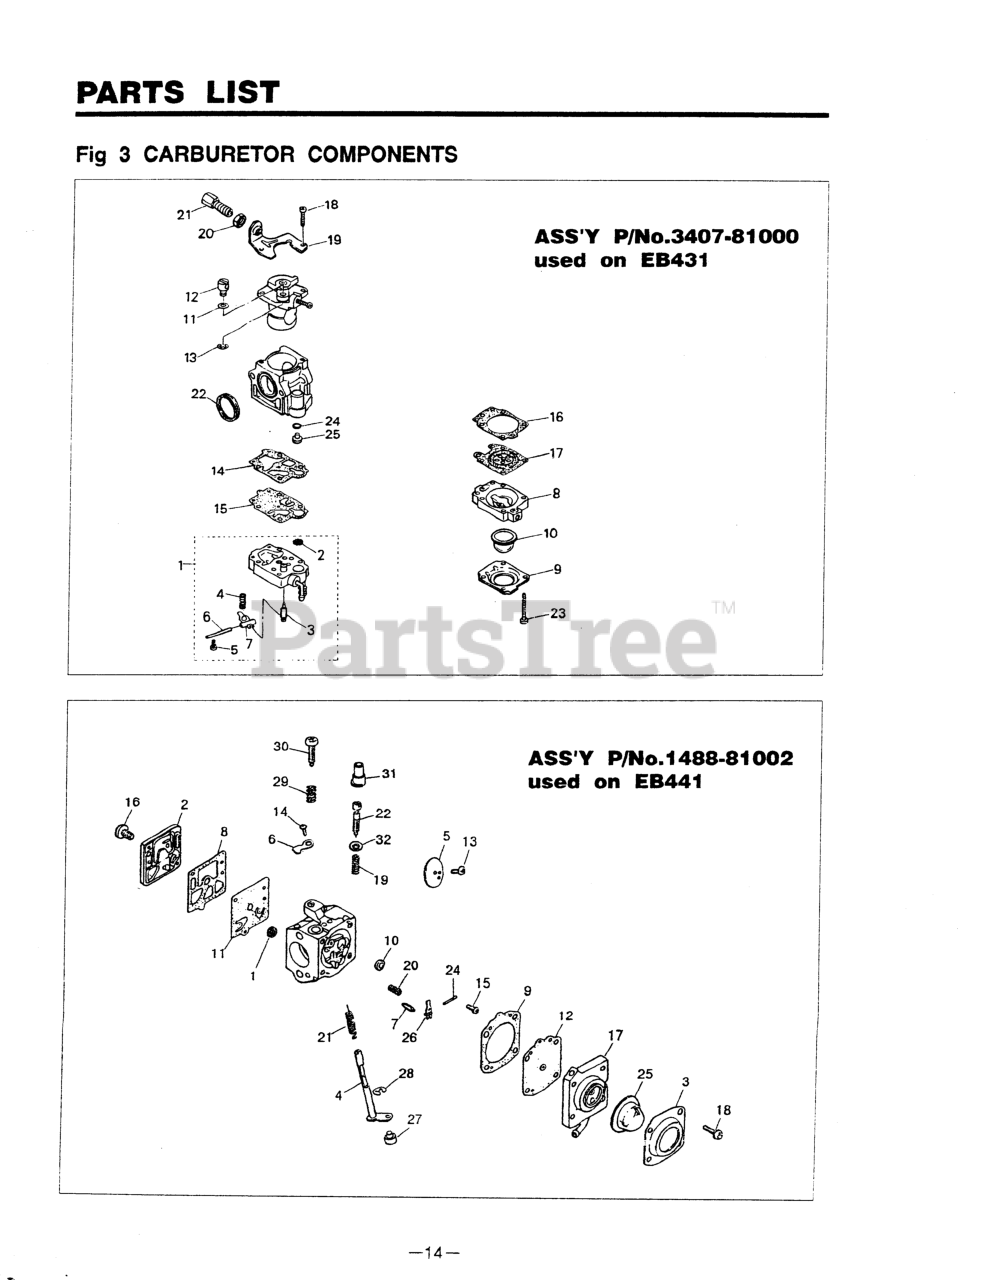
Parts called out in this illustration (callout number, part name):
1	BODY, PUMP
3	VALVE, INLET
4	SPRING, METERING LEVER
5	SCREW, METERING LEVER PIN
6	PIN, METERING LEVER
7	LEVER
8	BODY, PURGE
9	COVER, PUMP
10	PUMP, PRIMING
11	WASHER
12	SWIVEL
13	RING
14	GASKET, PUMP
15	DIAPHRAGM
16	GASKET, DIAPHRAGM
17	DIAPHRAGM (USE 4810-81260)
18	SCREW
20	NUT, CABLE ADJUSTER
21	SCREW, CABLE ADJUSTER
22	RING, PACKING
23	SCREW
25	RING, O
NI	CARBURETOR ASSEMBLY
